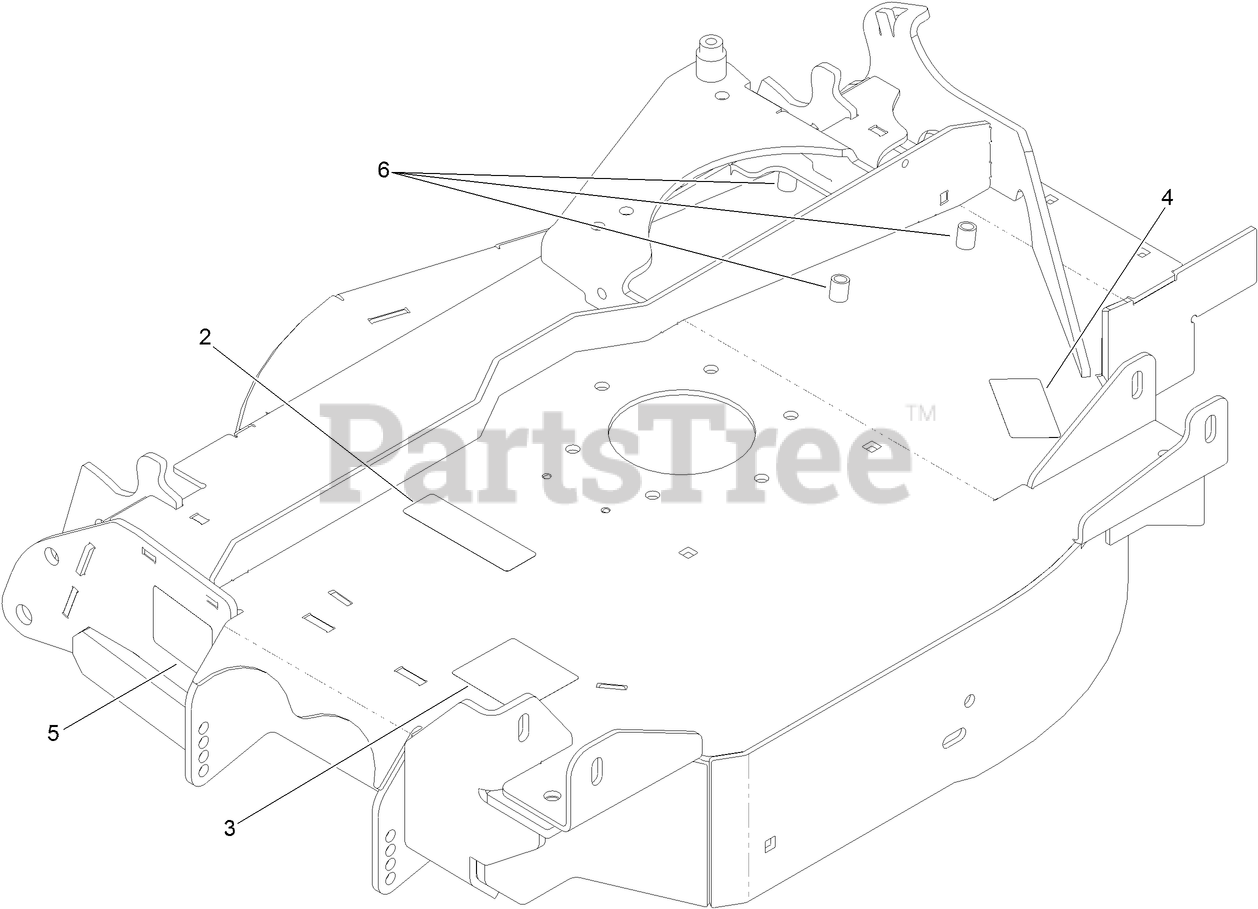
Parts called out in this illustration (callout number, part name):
2	DECAL-COVER, MISSING
3	DECAL-DANGER, THROWN OBJECT
4	DECAL-BOLT TORQUE
5	DECAL-WARNING, PINCH POINT
6	NUT-CLINCH
